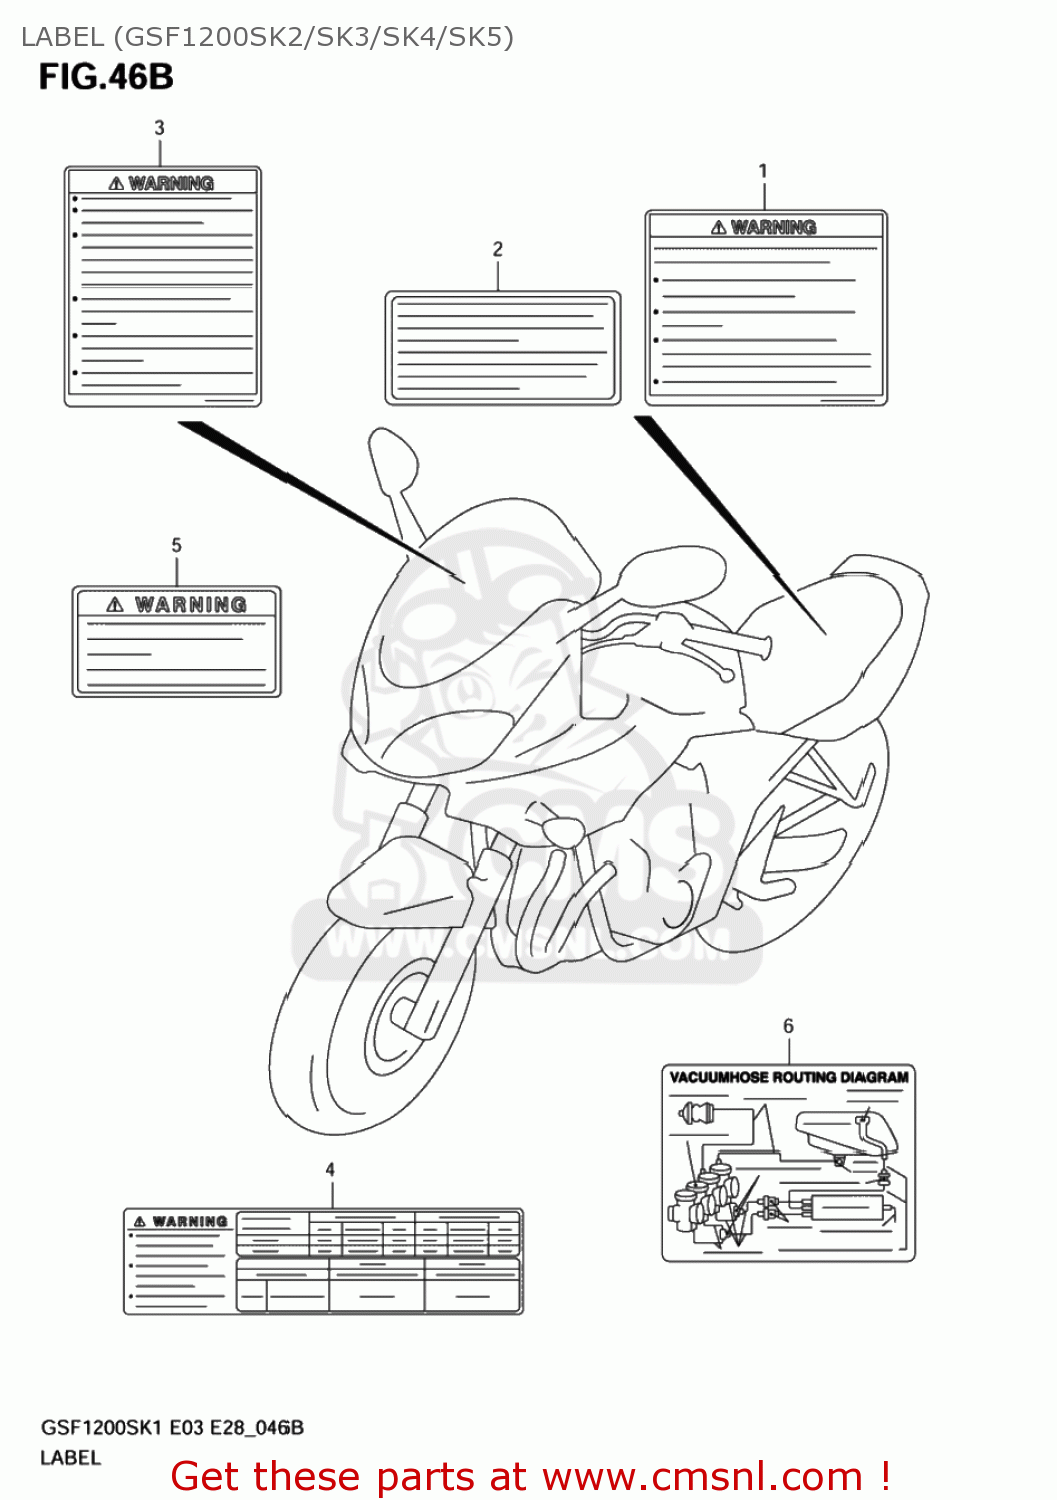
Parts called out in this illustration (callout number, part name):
1	LABEL,GENERAL WARNING
2	LABEL,MANUAL NOTICE
3	LABEL,SCREEN
4	LABEL,TIRE INFORMATION
5	LABEL,WARNING STEERING
6	LABEL,VACUUM HOSE ROUTING
7	MANUAL,OWNER'S
